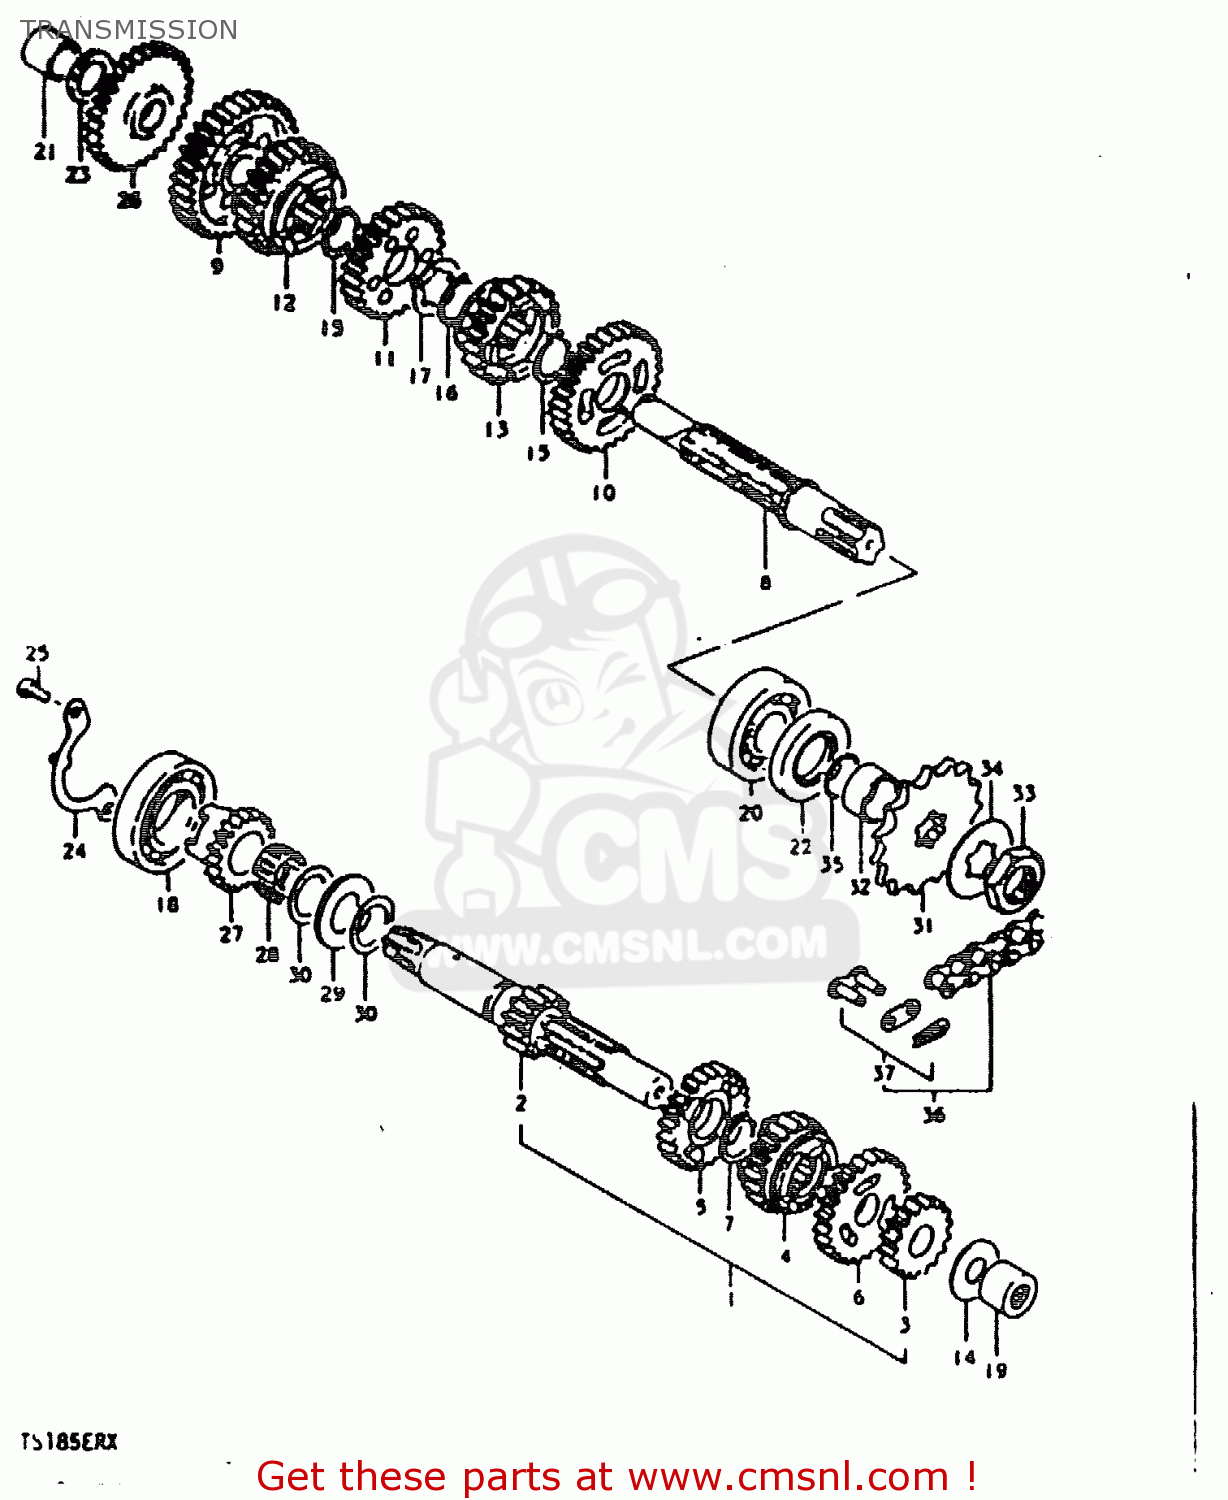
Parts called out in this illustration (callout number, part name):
1	SHAFT,COUNTER
2	SHAFT,COUNTER
3	GEAR,2ND DRIVE
4	GEAR,3RD DRIVE
5	GEAR,FOURTH DRIVE
6	GEAR,5TH DRIVE
7	CIRCLIP
8	SHAFT,DRIVE
9	GEAR,1ST DRIVEN
10	GEAR,2ND DRIVEN
11	GEAR,THIRD DRIVEN
12	GEAR,FOURTH DRIVEN
13	GEAR,FIFTH DRIVEN
14	WASHER
15	CIRCLIP
16	CIRCLIP
17	WASHER
18	BEARING, RH
19	BEARING(15X22X15)
20	BEARING
21	BUSH
22	OIL SEAL (25X44X7)
23	WASHER
24	RETAINER,CNTR SHAFT BEARING
25	SCREW 6X12
26	GEAR,KICK STARTER IDLE
27	GEAR,KICK STARTER DRIVEN
28	BEARING(19.2X23.2X19)
29	BEARING(21X32X2.85)
30	WASHER(21X30X0.8)
31	SPROCKET,ENGINE
32	SPACER(20X25X12.5)
33	NUT
34	WASHER,LOCK
35	O RING(D:1,ID:19.5)
36	CHAIN ASSEMBLY,DRIVE
37	JOINT
